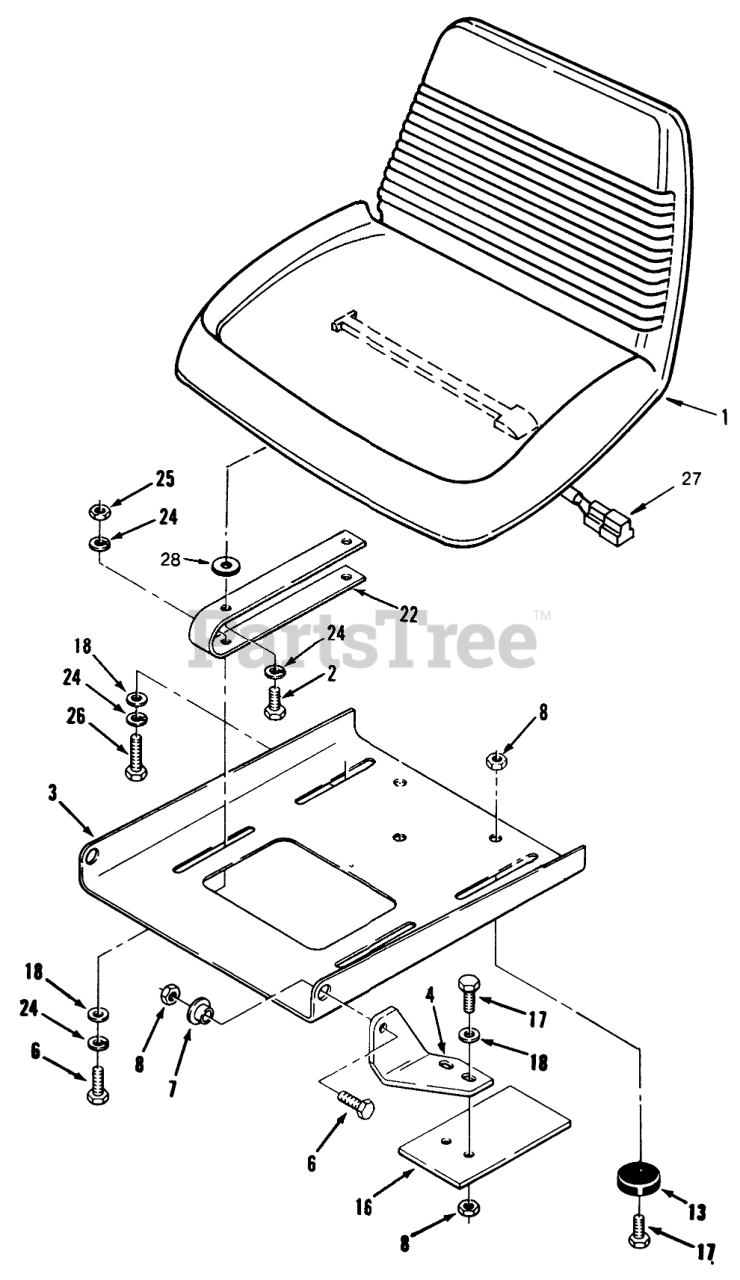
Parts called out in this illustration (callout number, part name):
1	SEAT V-510
2	Bolt
3	PLATE-SEAT PIVOT B
4	BRACKET-PIVOT L.H B
6	SCREW-HH
7	BUSHING
8	NUT-LOCK, NI
13	BUMPER
16	PLATE R
17	SCREW-HH
18	WASHER-PLAIN
22	SPRING-SEAT B
24	WASHER-LOCK
25	NUT-HEX
26	SCREW-HH
27	SWITCH-SEAT
28	SPACER-NYLON
